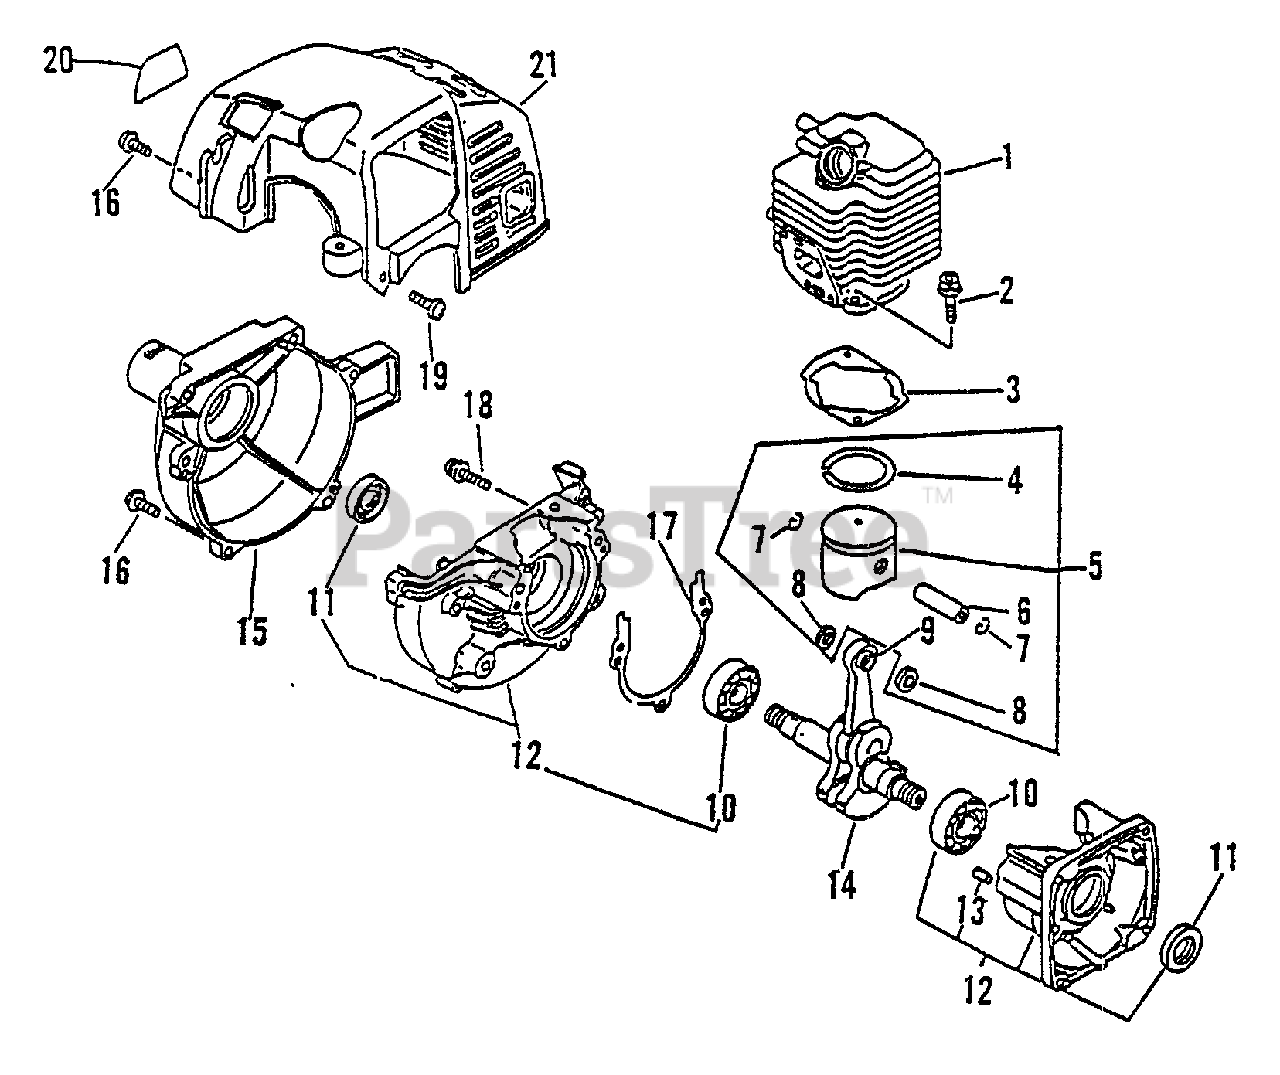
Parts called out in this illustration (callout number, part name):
2	BOLT 5×22
3	GASKET, CYLINDER
4	RING, PISTON
5	PISTON KIT
6	PIN, PISTON 8
7	RING, SNAP
8	WASHER, THRUST
9	BEARING, NEEDLE
10	BEARING, BALL - 6201 C3
11	SEAL, OIL 12
12	CRANKCASE KIT
13	PIN, LOCATING 4
14	CRANKSHAFT ASSY
15	CASE, FAN
16	SCREW 4×16
17	GASKET, CRANKCASE
18	SCREW 5×28
19	SCREW 4×12
20	LABEL, LST-2100
21	COVER, ENGINE
